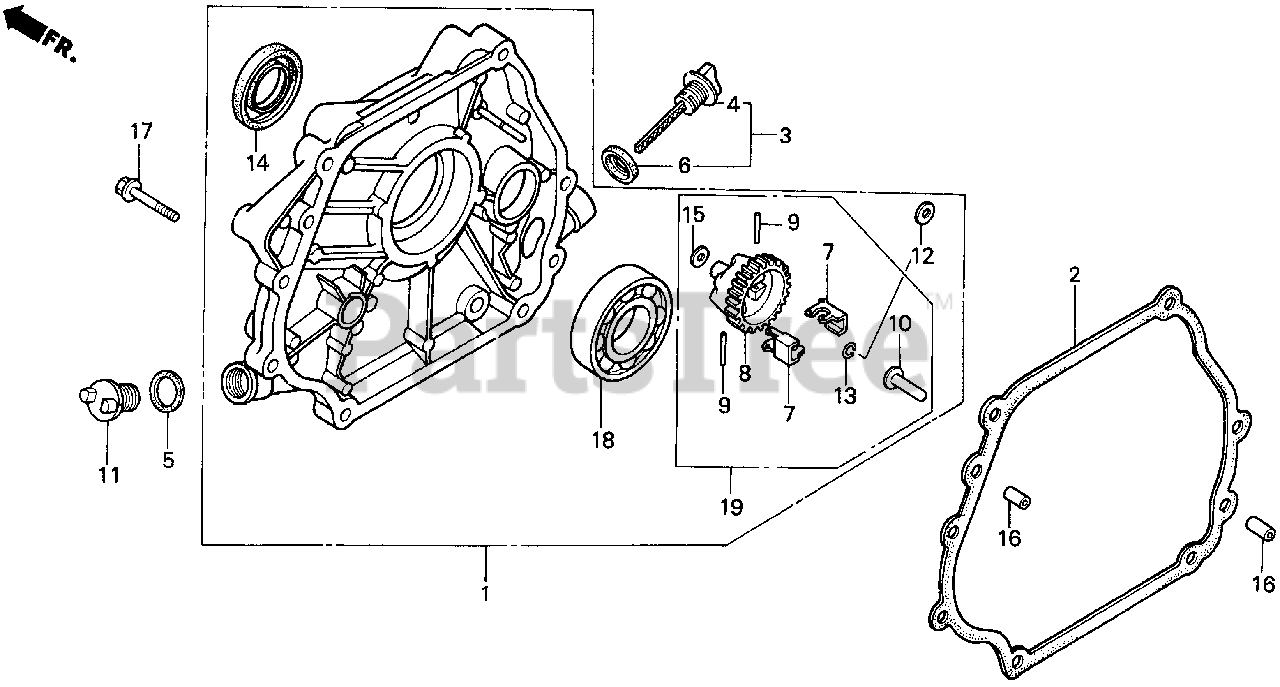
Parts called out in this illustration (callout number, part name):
1	COVER ASSY., CRANKCASE (S-TYPE)
1	COVER ASSY., CRANKCASE
2	GASKET, CASE COVER
3	CAP ASSY., OIL FILLER
4	CAP, OIL FILLER
5	GASKET, OIL FILLER CAP
6	GASKET, OIL FILLER CAP
7	WEIGHT, GOVERNOR
8	HOLDER, GOVERNOR WEIGHT
9	PIN, GOVERNOR WEIGHT
10	SLIDER, GOVERNOR
11	CAP, OIL FILLER
11	CAP, OIL HOLE
12	WASHER (6X16)
13	CLIP, GOVERNOR HOLDER
14	OIL SEAL (30X46X8)
15	WASHER, PLAIN (6MM)
16	PIN, DOWEL (8X12)
16	PIN A, DOWEL (8X12)
16	PIN A, DOWEL (8X14)
17	BOLT, FLANGE (8X35)
18	BEARING, RADIAL BALL (6206)
19	GOVERNOR KIT (STD)
